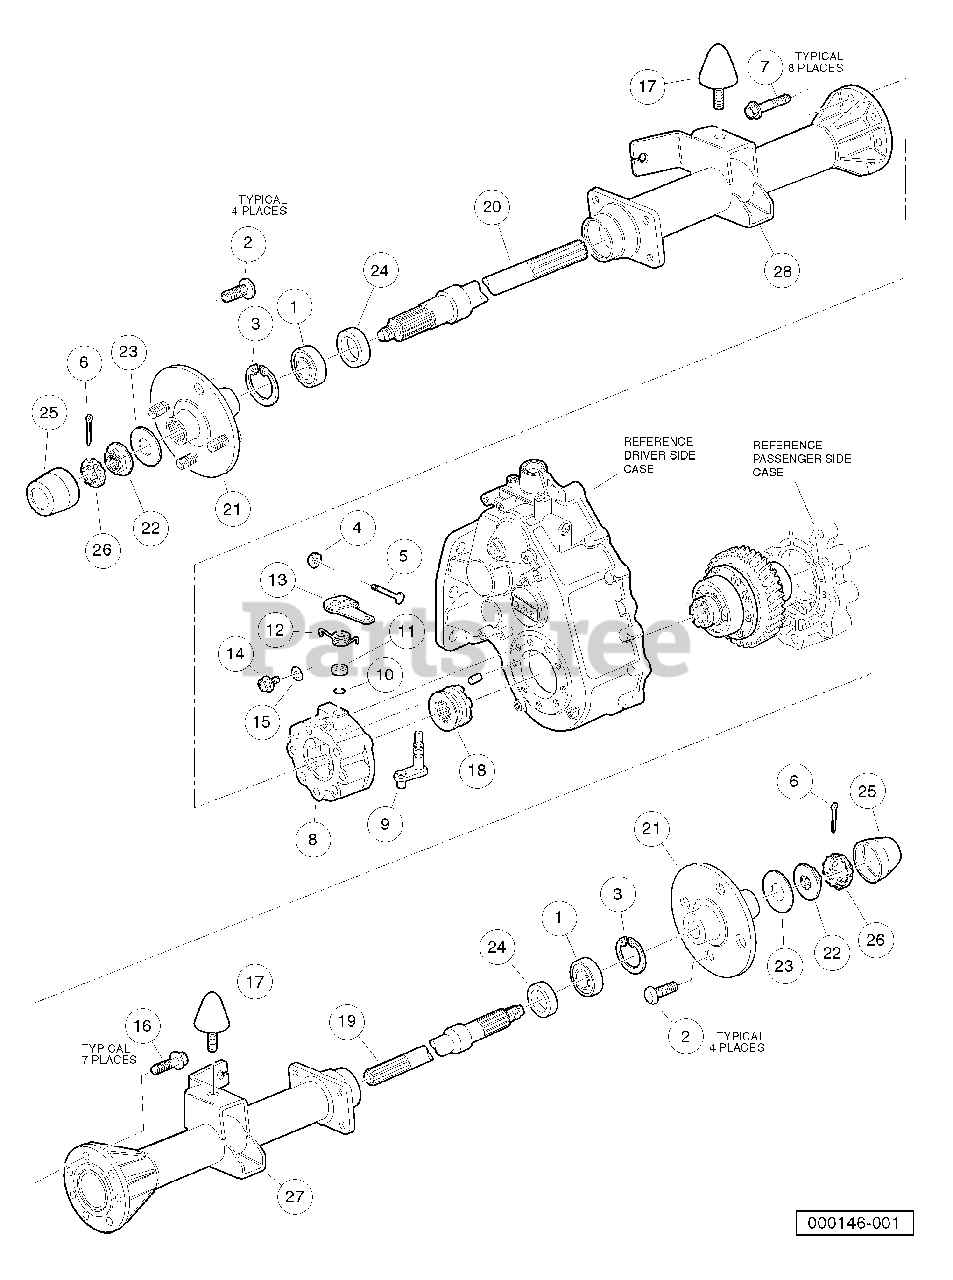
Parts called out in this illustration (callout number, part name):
1	Outer Axle, Tube Bearing
3	Circlip Type C
5	Bolt, M6 Special
6	Pin, Cotter, 0.312 x 1.25
7	Bolt, M10 X 1.5 X 70mm
8	Housing, Differental Lock
9	Lever, Differental Lock
11	Spacer, Differental Lock
12	Spring, Differental Lock
13	Arm Lever, Differental Lock
14	Screw, M6 X 1 X 10mm
16	Bolt, M10 X 1.5 X 30mm
17	Stud Mount
18	Shifter, 15-Tooth
19	Axle Shaft - Rh
20	Axle Shaft - l_h
21	Wheel Bolt Flange
22	Nut, Flange
23	Washer - Axle
25	Center Cap, Rubber
26	Locking Cap, Nut
27	Axle Tube, Hd, Rh
28	Axle Tube, Hd, Lh
